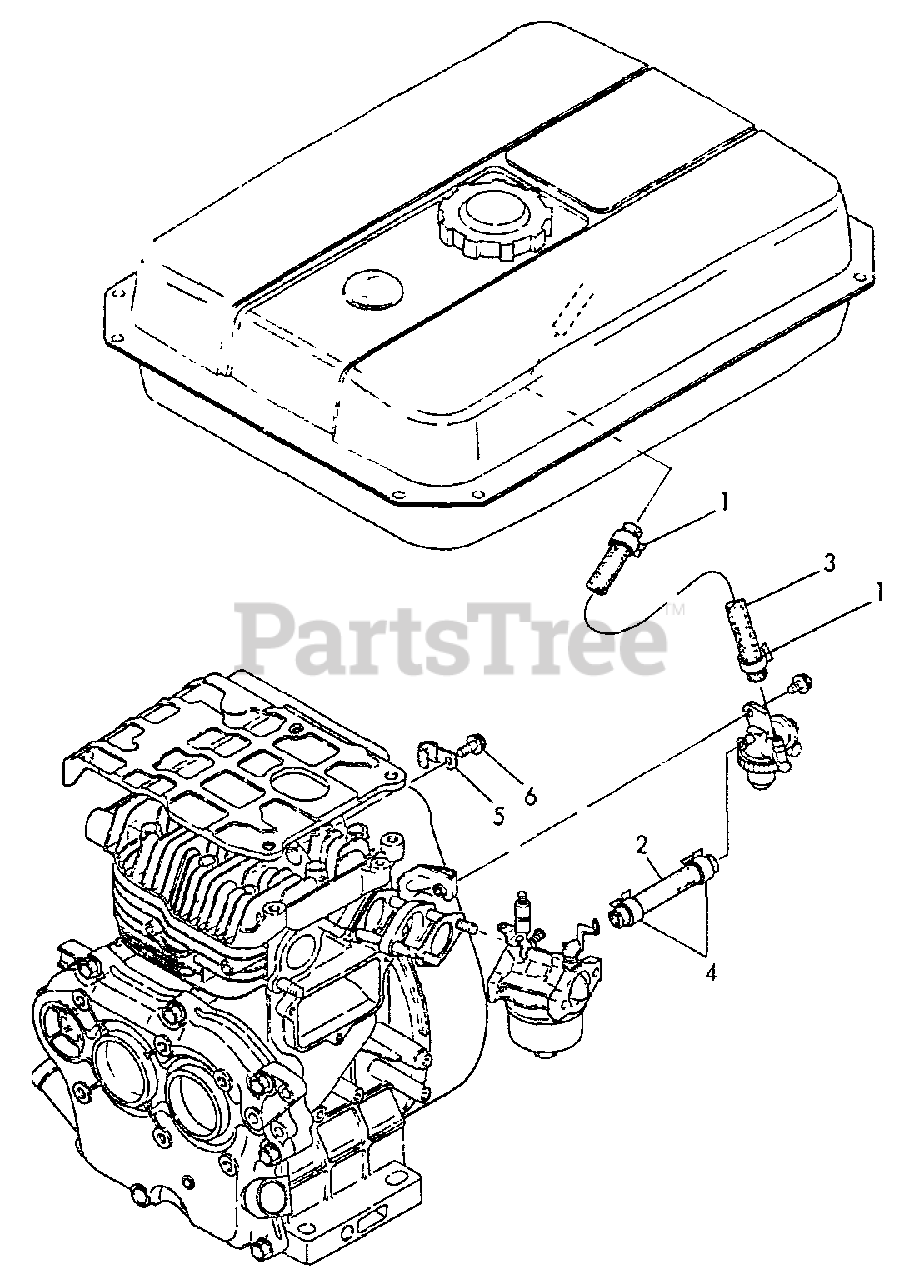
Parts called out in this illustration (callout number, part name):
1	CLAMP, HOSE
2	PIPE, FUEL
3	PIPE, FUEL
4	CLAMP
5	CLAMP
6	BOLT - 6×8 -- PLATED
